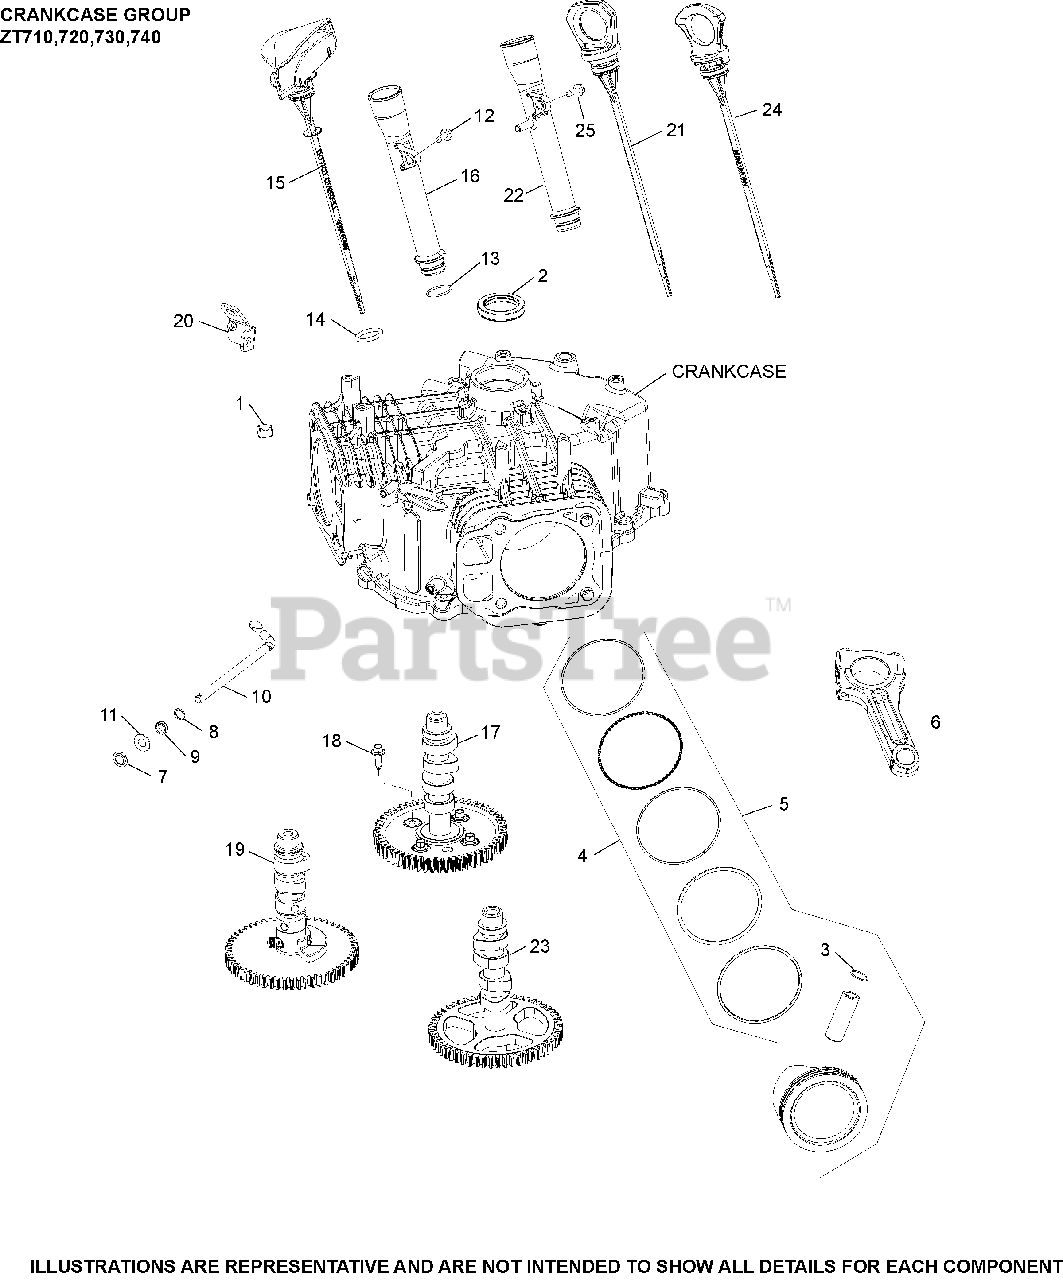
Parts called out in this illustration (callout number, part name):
1	PIN, LOCATING
2	SEAL, OIL (HELIX LIP)
3	RETAINER, PISTON PIN
4	RING SET(STD)STYLE B-1.2mm Tp RING THICK
4	RING SET(.08)STYLE B-1.2mm Tp RING THICK
4	RING SET(.25)STYLE B-1.2mm Tp RING THICK
4	RING SET(.50)STYLE B-1.2mm Tp RING THICK
5	PISTON W/RINGS (STYLE B)(STD) - RING SET 25 108 01-S
5	PISTON W/RINGS (STYLE B)(.08) - RING SET 25 108 02-S
5	PISTON W/RINGS (STYLE B)(.25) - RING SET 25 108 03-S
5	PISTON W/RINGS (STYLE B)(.50) - RING SET 25 108 04-S
6	ROD, ASSY CONNECTING (STD)-(#2406730S)
6	ROD ASSY, CONNECTING U/S (.010”) (.25 mm) -USE 24 067 31-S
8	WASHER, FLAT 11/32"
9	SEAL, GOVERNOR CROSS SHAFT
10	KIT, CROSS SHAFT
11	WASHER, FLAT 9 MM
16	TUBE ASSEMBLY, OIL FILL
20	BRACKET, OIL FILL TUBE
23	CAMSHAFT ASSEMBLY
24	DIPSTICK, ASSEMBLY
25	SCREW, THREAD FORMING
